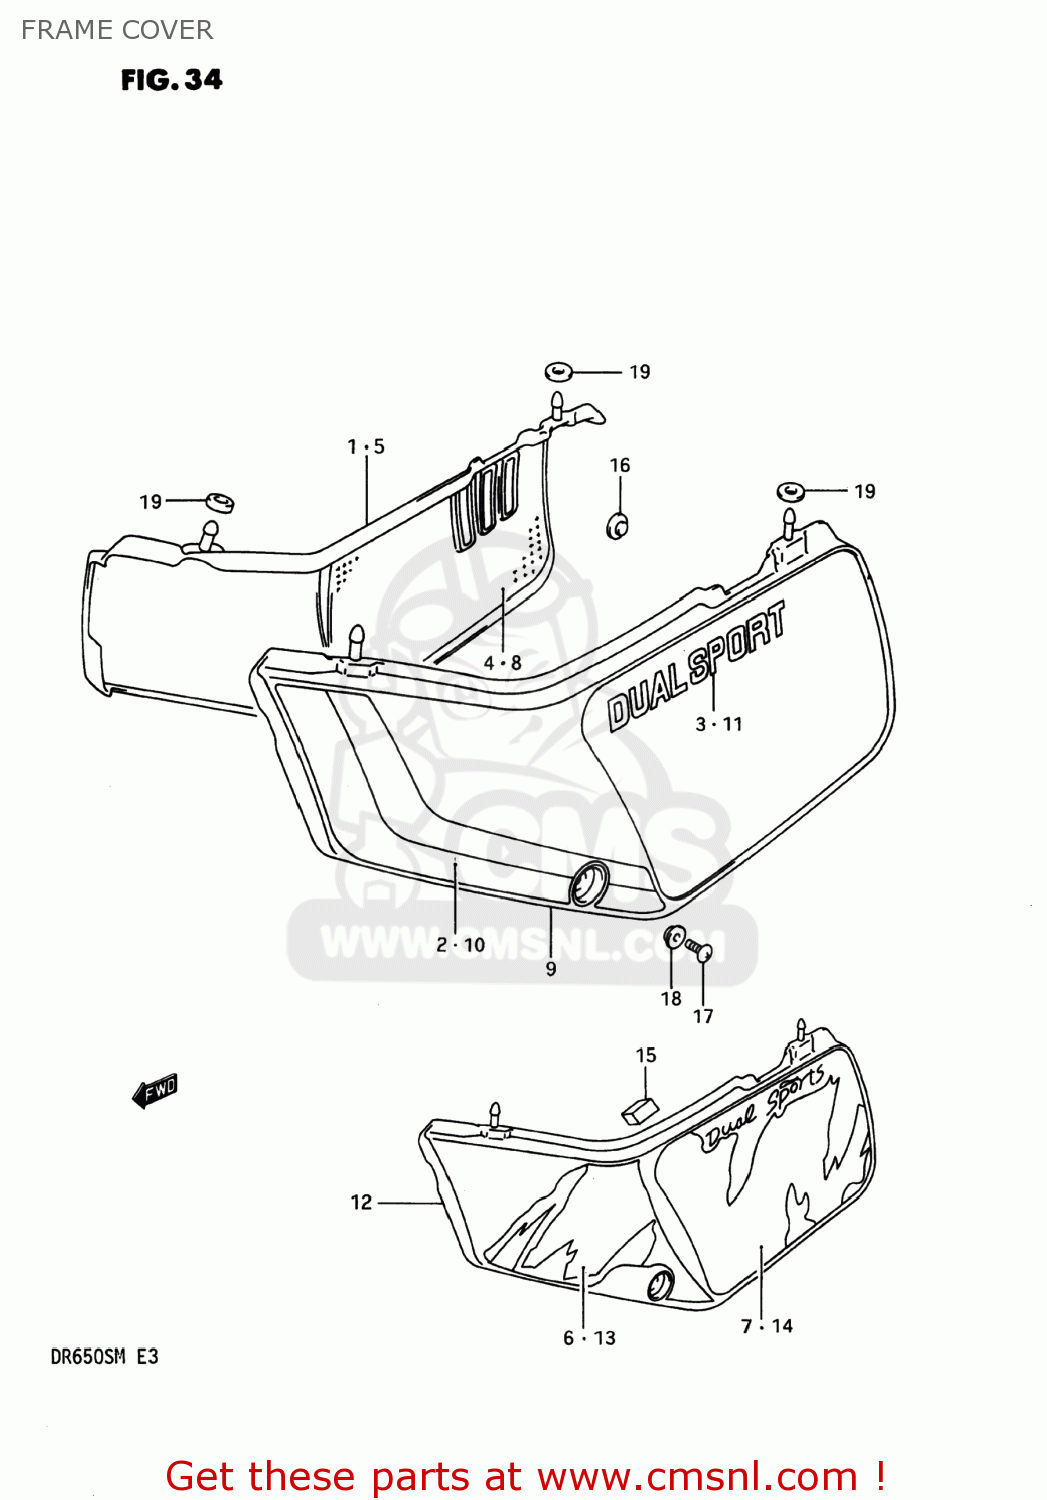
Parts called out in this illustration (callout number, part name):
1	COVER,SIDE,RIGHT
2	TAPE,FRAME COVER,RIGHT
3	EMBLEM,FRAME COVER
4	SHIELD,FRAME COVER,RIGHT
5	COVER COMP,SIDE,RIGHT
6	TAPE,FRAME COVER SIDE,RIGHT
7	EMBLEM
8	SHIELD,FRAME COVER,RIGHT
9	COVER,SIDE,LEFT
11	EMBLEM,FRAME COVER
12	COVER COMP,SIDE,LEFT
13	TAPE,FRAME COVER SIDE,LEFT
14	EMBLEM,FRAME COVER
15	CUSHION,FRAME COVER
16	CUSHION
17	SCREW 6X12
18	WASHER
19	CUSHION,SIDE COVER BOSS
